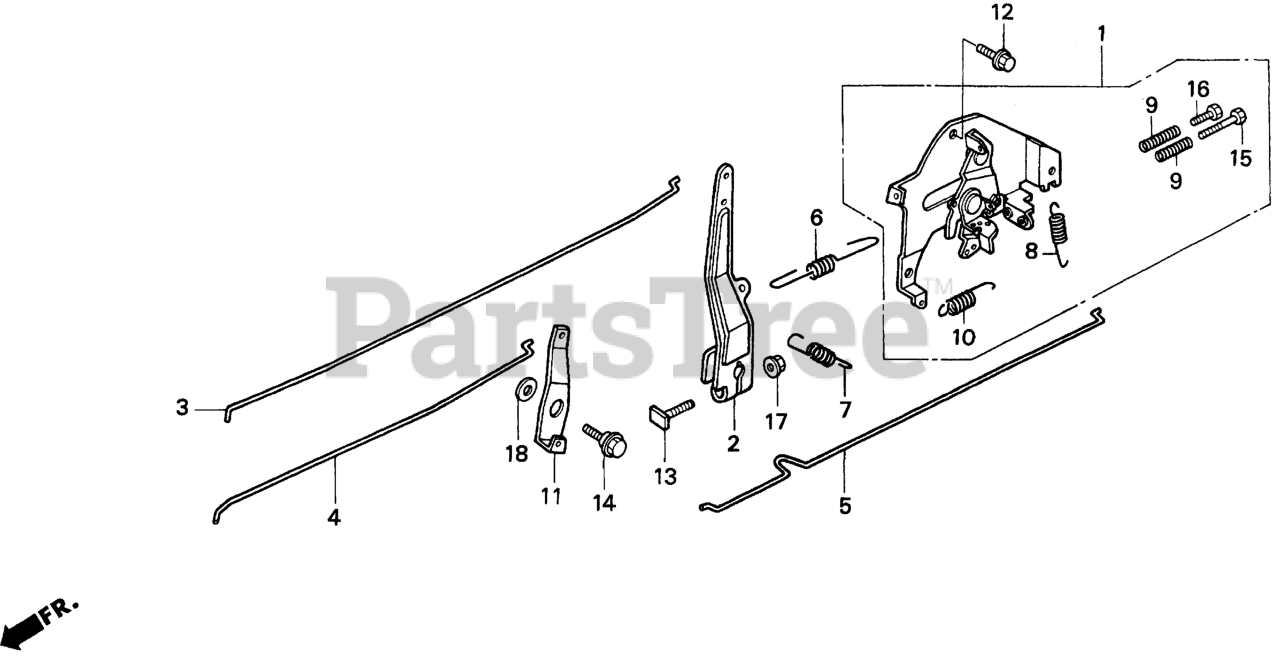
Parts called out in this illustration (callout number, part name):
1	CONTROL ASSY.
2	ARM, GOVERNOR
3	ROD, GOVERNOR
4	ROD, CHOKE
5	ROD, JOINT
6	SPRING, GOVERNOR
7	SPRING, GOVERNOR PRIMARY
8	SPRING, LEVER
9	SPRING, CONTROL ADJUSTING Use from Engine SN 2327377.
10	SPRING, CABLE RETURN
11	LEVER, CHOKE JOINT
12	BOLT, FLANGE (6X12) (CT200)
13	BOLT, GOVERNOR ARM
14	BOLT, FLANGE (6MM)
15	BOLT, RECESSED (5X34)
16	BOLT, HEX. (5X20)
17	NUT, FLANGE (6MM)
18	WASHER, PLAIN (6MM)
